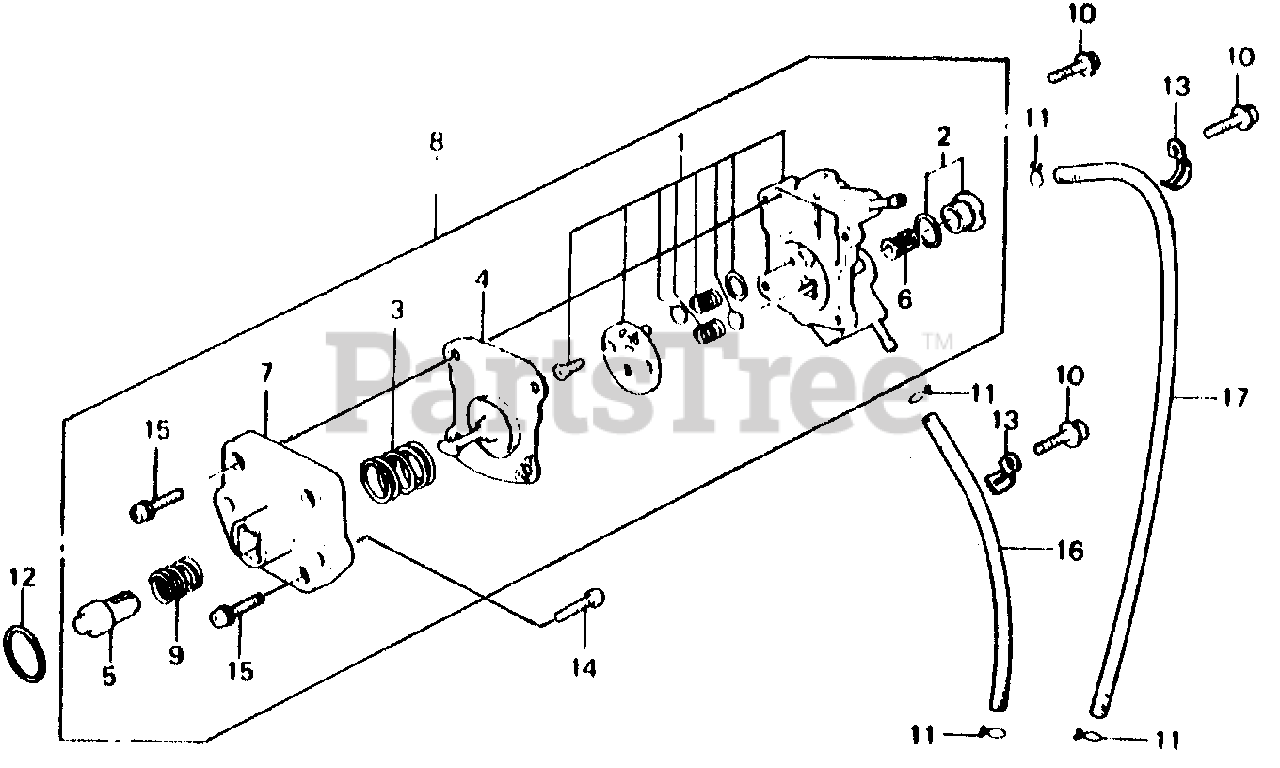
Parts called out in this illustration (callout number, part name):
1	BODY SET, PUMP
2	BOLT SET, HOLDING
3	SPRING, DIAPHRAGM
6	SCREEN, FUEL STRAINER
7	BODY (LOWER)
8	PUMP ASSY., FUEL (MSDS)
9	SPRING, PUSH ROD
10	BOLT, FLANGE (6X28)
11	CLIP, TUBE (B8)
12	O-RING (20.8X2.4)
13	CLIP B, CORD
14	SCREW, PAN (6X20)
15	SCREW-WASHER (4X16)
16	BULK HOSE, FUEL (4.5X3000) (4.5X320)
17	BULK HOSE, FUEL (4.5X3000) (4.5X400)
